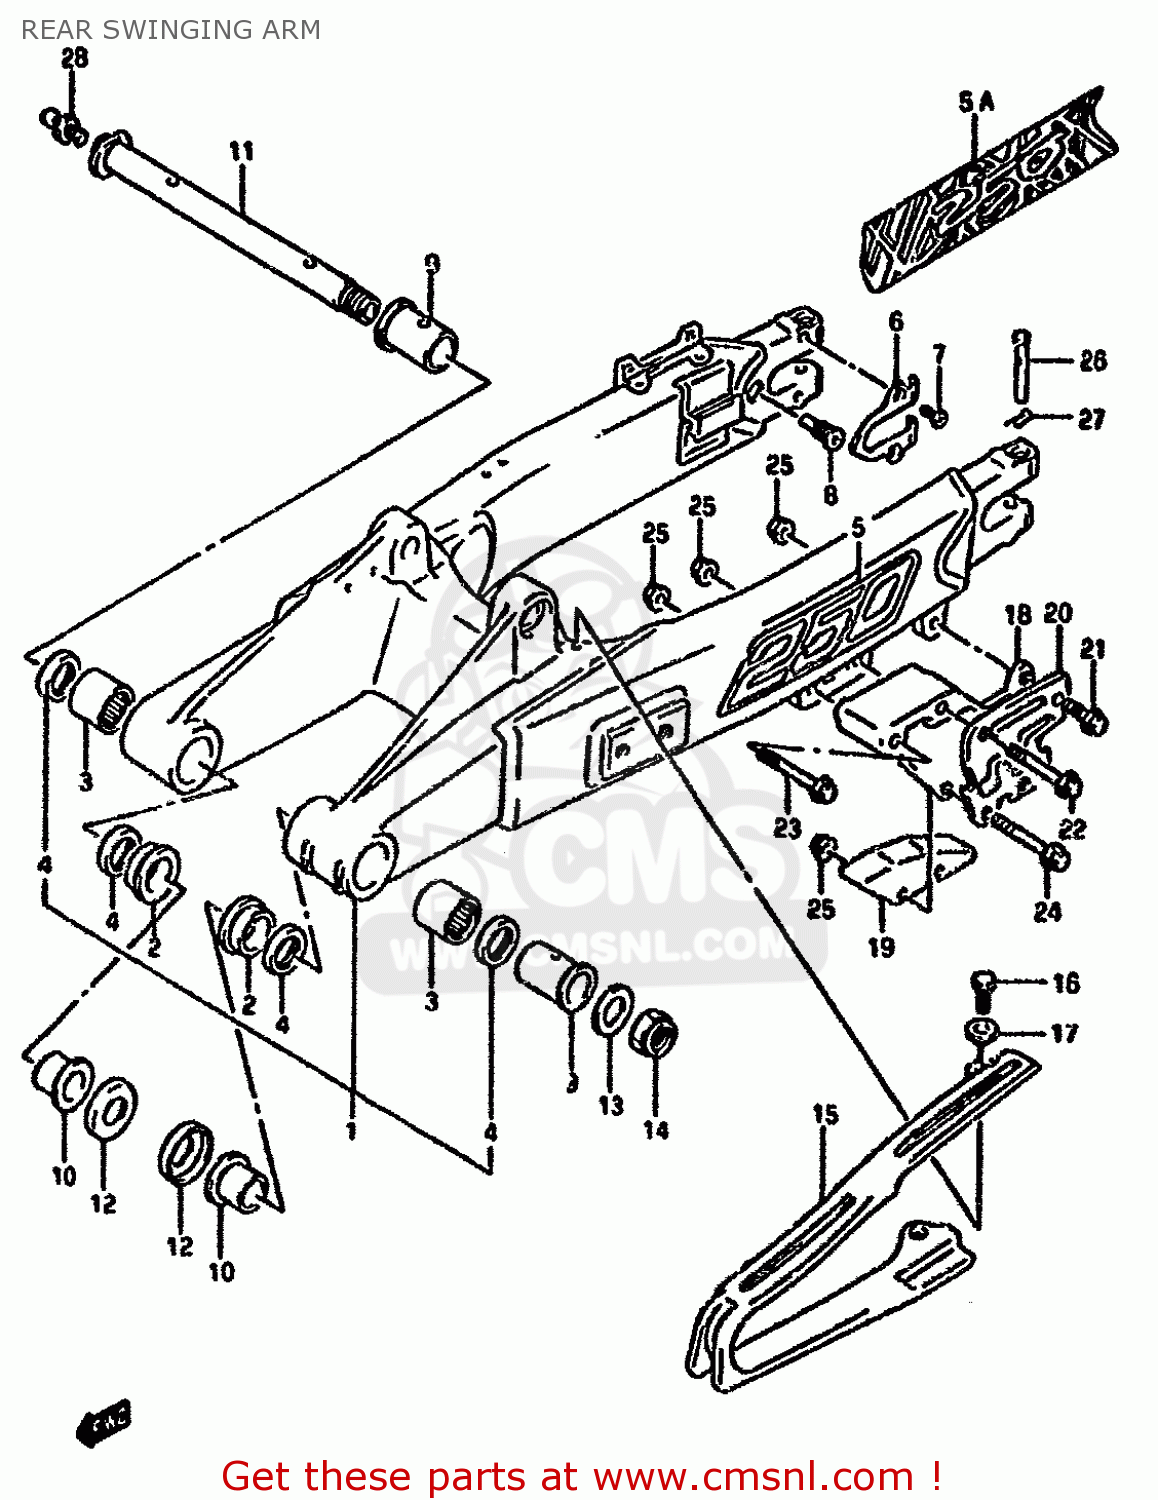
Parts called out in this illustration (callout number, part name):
1	SWING ARM ASSEMBLY,REAR
2	BUSHING,SWGARM PIVOT
3	BEARING(22X29X30)
4	SEAL,OIL(22X29X4)
5	EMBLEM,SWINGINGARM
5A	EMBLEM (250)
6	PLATE,RR SWING ARM AXLE
7	SCREW
8	SCREW (M10X21)
9	SPACER,RR SWGARM PIVOT
10	SPACER,SWGARM PIVOT INNER
11	SHAFT COMP,SWING ARM PIVOT
12	COVER,SWINGINGARM PIVOT
13	WASHER
14	NUT
15	BUFFER,CHAIN TOUCH DEFENSE
16	BOLT
17	WASHER
18	GUIDE,CHAIN
19	DEFENSE,CHAIN GUIDE
20	PLATE,CHAIN GUIDE OUTER
21	BOLT
22	BOLT
23	BOLT
24	BOLT
25	NUT
26	PIN
27	CLIP
28	NIPPLE
